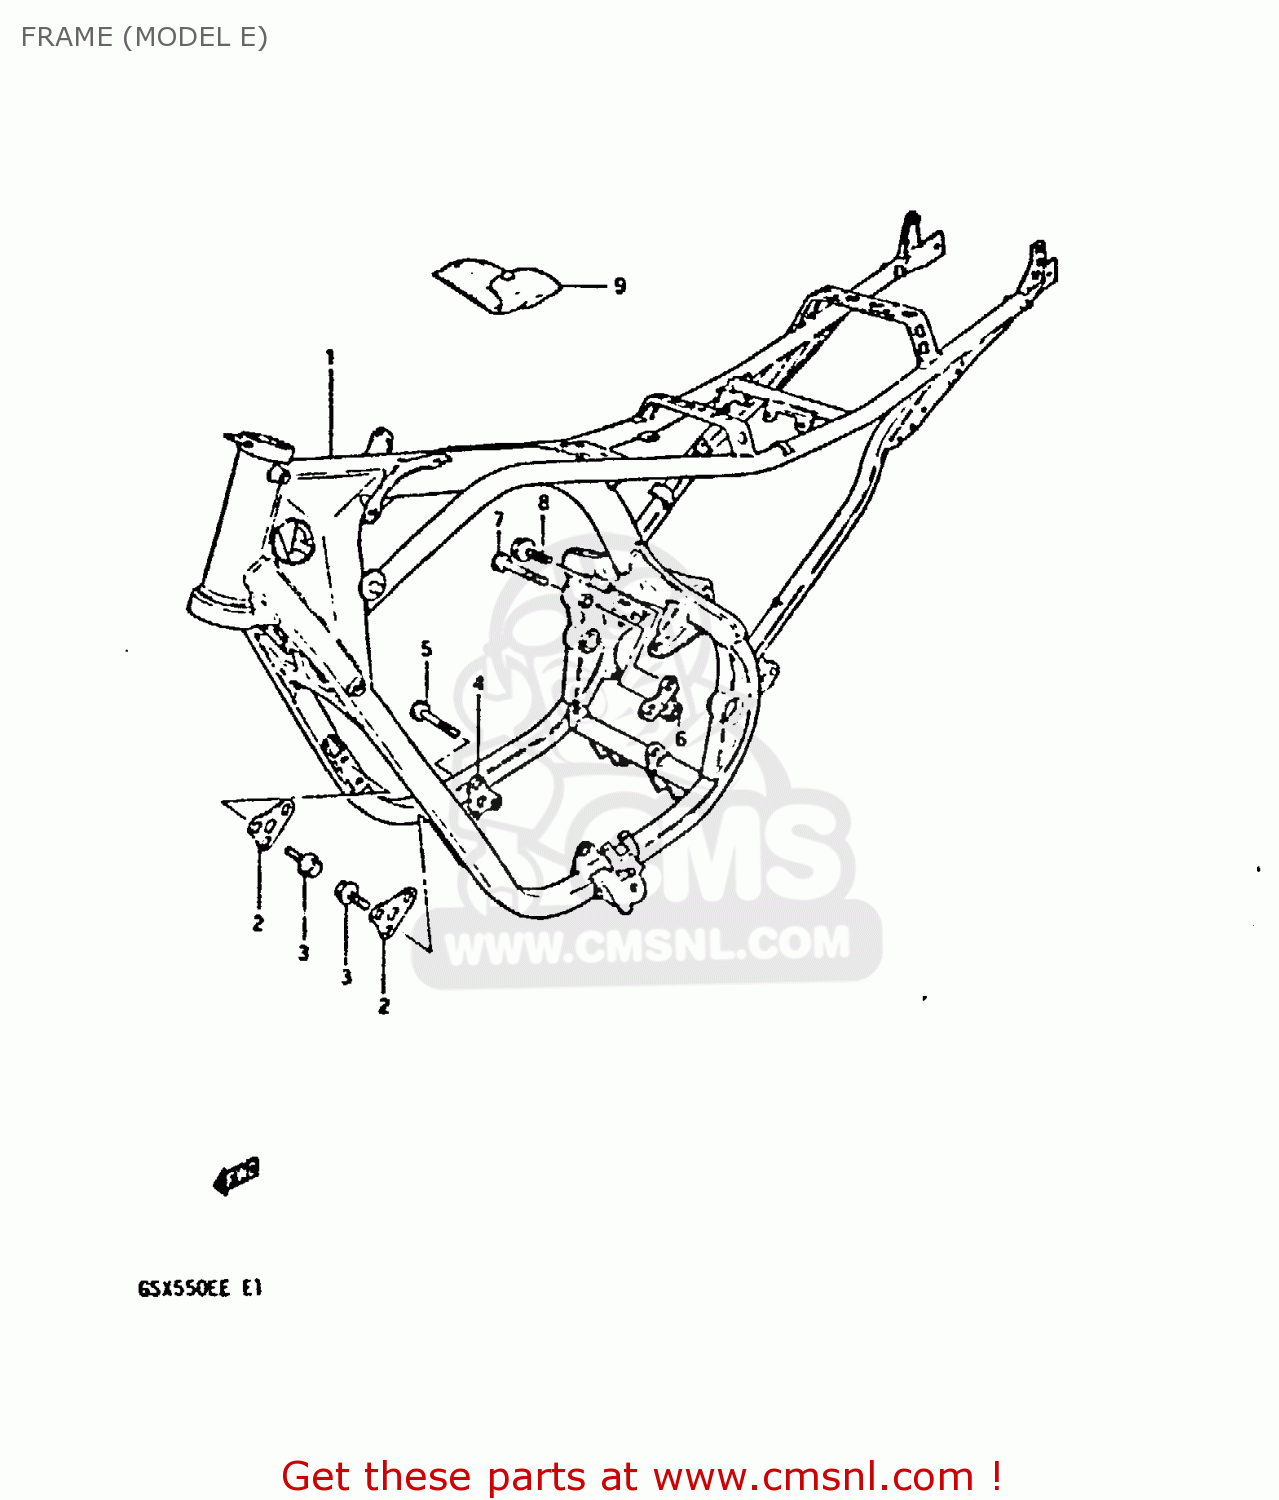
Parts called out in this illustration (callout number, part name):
1	FRAME
2	PLATE,ENGINE MOUNTING NO
3	BOLT
4	PLATE,ENGINE MOUNTING NO
5	BOLT
6	PLATE,ENGINE MOUNTING NO.4
7	BOLT
8	BOLT
9	TOOL ASSY
